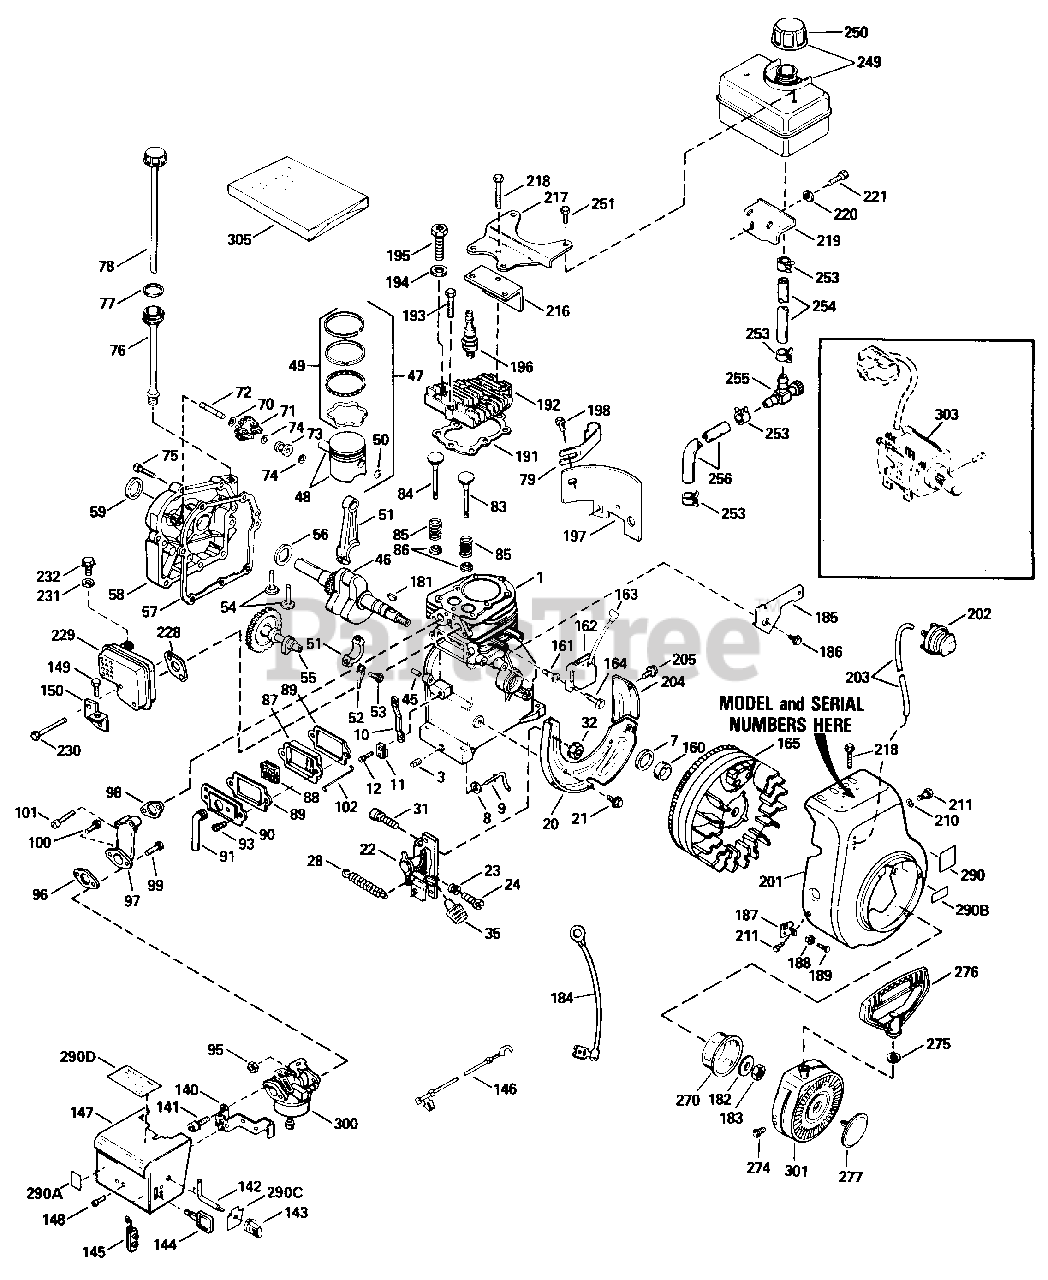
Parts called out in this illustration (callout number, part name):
1	Cylinder Ass'y.
3	Plug, Pipe, 1/4-18
7	Seal, Oil
8	Washer, Flat
9	Rod, Governor
10	Lever, Governor
11	Clamp, Governor Lever
12	Screw, Hex Washer Hd., 8/32 x 5/16
20	Baffle, Blower Housing
21	Screw, Hex Washer Hd. Durlok, 1/4-20 x 5/8
22	I Control Ass'y., Bracket
23	Spring, Compression
24	Screw, Fil. Hd., 5-40 x 7/16
28	Spring, Extension
31	Screw, Fil. Hd. Sems, 8/32 x 1/2
32	Nut, Lock, 8/32
35	Knob, Speed Control
45	Pin, Dowel
46	Crankshaft Ass'y.
47	Piston, Pin & Ring Ass'y. (Std.)
48	Piston & Pin Ass'y. (Std.)
49	Ring Set, Piston (Std.)
50	Ring, Piston Pin Retaining
51	Rod Ass'y., Connecting
52	Dipper, Oil
53	Bolt, Connecting Rod
54	Lifter, Valve
56	Washer, Thrust
57	Gasket, Cylinder Cover
58	Cover, Cylinder
59	Seal, Oil
70	Washer, Flat
71	Gear, Governor
72	Shaft, Mechanical Governor
73	Spool, Governor
74	Ring, Retaining
75	Screw, Hex Hd. Sems, 1/4-20 x 11/4
76	Tube Ass'y., Oil Fill
79	Clip, Oil Fill
83	Valve, Exhaust (Std.)
84	Valve, Intake (Std.)
85	Spring, Valve
86	Cap, Valve Spring
87	Body, Valve Cover
88	Element, Valve Body
89	Gasket, Valve Cover
90	Cover, Breather
91	Tube, Breather
93	Screw, Fil. Hd. Sems, 10-24 x 1/2
95	Nut & Lock Washer Ass'y. 1/4-28
96	Gasket, Carburetor
97	Pipe, Intake
98	Gasket, Intake
99	Screw, Hex Hd., 1/4-28 x 7/8
100	Screw, Hex Hd., 1/4-28 x 1-11/16
101	Screw, Fil. Hd. Sems, 1/4-20 x 1 -1 9/32
102	Link, Governor to Throttle
140	Bracket, Choke
141	Screw, Fil. Hd. Sems, 10-32 x 1/2
142	Rod, Choke
143	Knob, Choke Control
144	Key, Ignition
145	Terminal Ass'y.
146	Wire, Ground
147	Cover, Carburetor
148	Screw, Pan Hd. Sems, 8/32 x 5/16
149	Screw, Hex Hd. Sems, Taptite, 10-24 x 3/8
150	Bracket, Carburetor Cover
160	Spacer, Flywheel Key
161	Stud, Solid State Mounting
162	Solid State Ass'y.
163	Cover, Spark Plug
164	Screw, Hex Hd. Sems, 10-24 x 1
181	Key, Flywheel
182	Washer, Belleville
183	Nut, Flywheel
184	Wire, Ground
185	Bracket, Hold Down
186	Screw, Hex Washer Hd. Self-Tap Sems, 10-24 x 9/16
187	Bracket, Grommet Mounting
188	Grommet, Plastic
189	Screw, Pan Hd. Taptite, 8/32 x 3/8
191	Gasket, Cylinder Cover
192	Head, Cylinder
193	Screw, Hex Flanged Hd., 5/16-18 x 1-1/2
194	Washer, Flat
195	Screw, Special Hex Hd., 5/16-18 x 1-1/2
196	Plug, Spark
197	Extension, Blower Housing
198	Screw, Fil. Hd. Sems, 10-24 x 1/2
201	Housing, Blower
202	Primer Ass'y.
203	Line, Primer
204	Extension, Baffle
205	Screw, Hex Washer Hd. Shake-proof Self-Drilling, 8-18 x 7/16
210	Washer, Flat
211	Screw, Hex Hd. Sems, 1/4-28 x 7/16
216	Baffle, Heat
217	Plate, Fuel Tank
218	Screw, Hex Flange Hd., 5/16-18 x 2
219	Bracket, Fuel Tank Mounting
220	Washer, Flat
221	Screw, Hex Hd. w/Belleville Washer, 1/4-20 x 11/16
228	Gasket, Exhaust
229	Muffler
230	Screw, Fil. Hd. Sems, 1/4-20 x 21/2
231	Washer, Flat
232	Screw, Hex Washer Hd. Sems, 1/4-20 x 1/2
249	Tank Ass'y., Fuel
250	Cap, Fuel Tank
251	Screw, Hex Washer Hd. Self-Tap Sems, 1/4-15 x 7/8
253	Clamp, Fuel Line
254	Line, Fuel
255	Valve, Shut-Off
256	Line, Fuel
270	Cup, Starter
274	Screw, Hex Wash. Hd. 8/32 x 1/2
275	Washer, Flat
276	Handle, Starter
277	Plug, Starter
290	Decal, Name
290A	Decal, Instruction
290B	Decal, Primer
290C	Decal, Choke
290D	Decal, Warning
300	Carburetor
301	Starter, Rewind
303	Electric Starter Kit
305	Gasket Set
